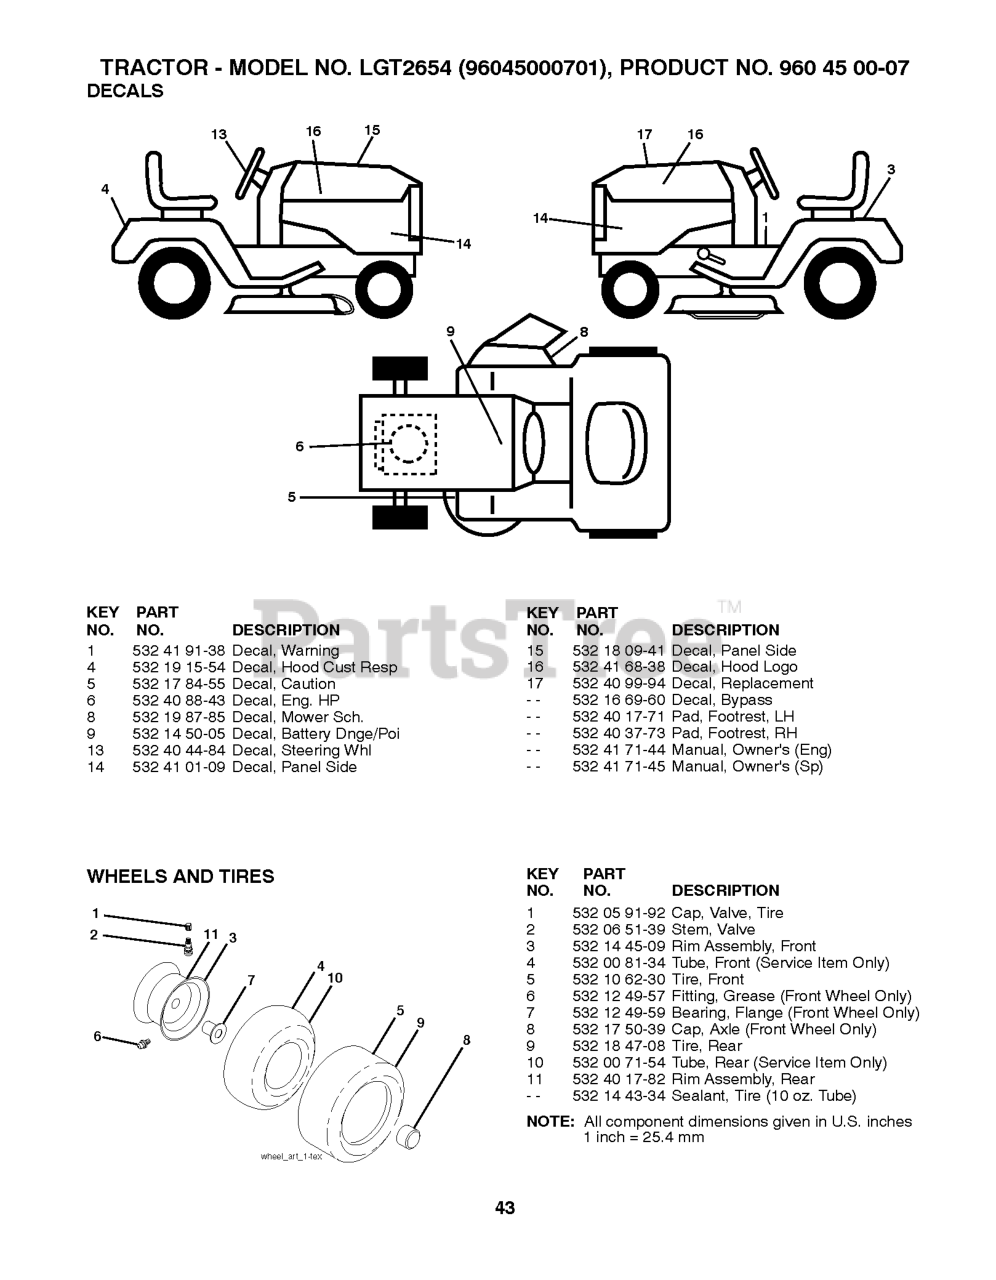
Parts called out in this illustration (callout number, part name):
2	VALVE STEM LT
3	RIM ASSEMBLY, FRONT
4	TUBE.16X6.5/7.5-8
5	TIRE HEAVY DUTY
6	FITTING LT
7	BEARING T
8	CAP, AXLE BLK
9	TIRE.22X9.50-12.TURF.SAVER.REA
10	TUBE.23X9.5-12
11	RIM.ASM.12".REAR.SILVER
